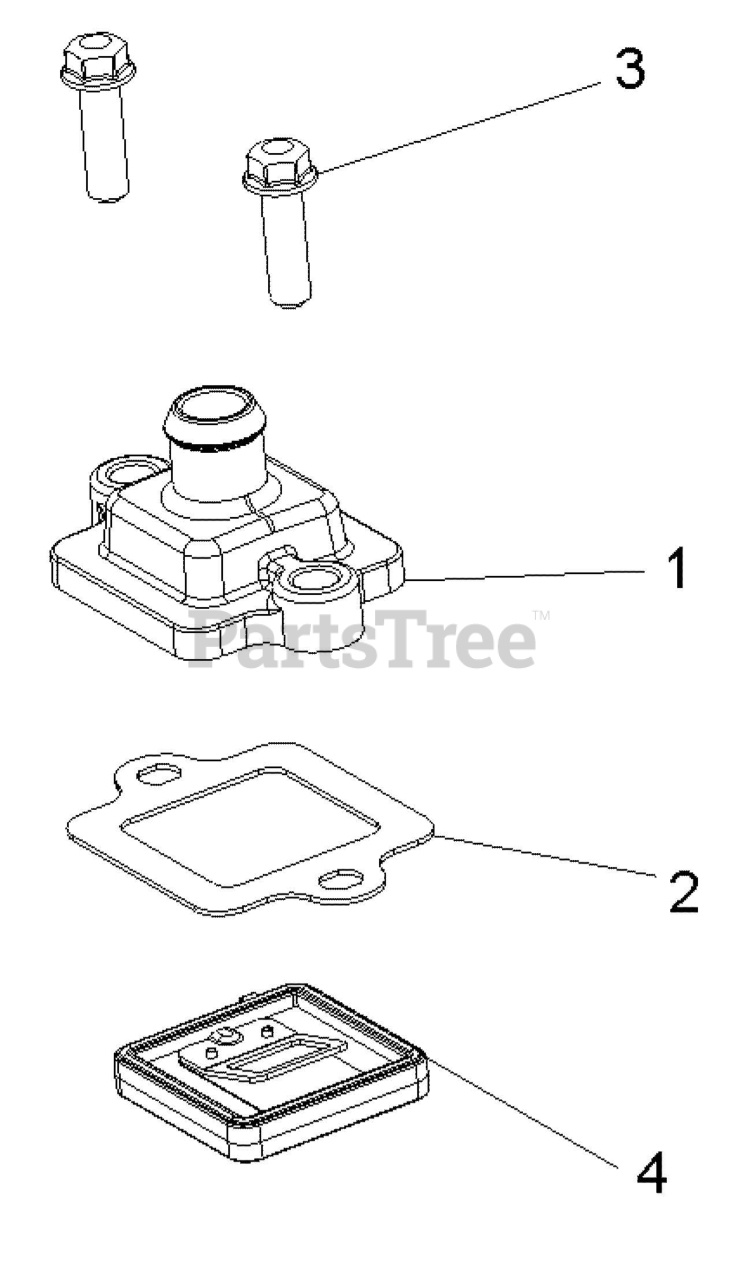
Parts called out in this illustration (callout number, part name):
1	COVER-BREATHER,MACH
2	GASKET-BREATHER,COVER
3	SCR-M6X20,HXFLG,0600214
4	ASM-REED W/GASKET
